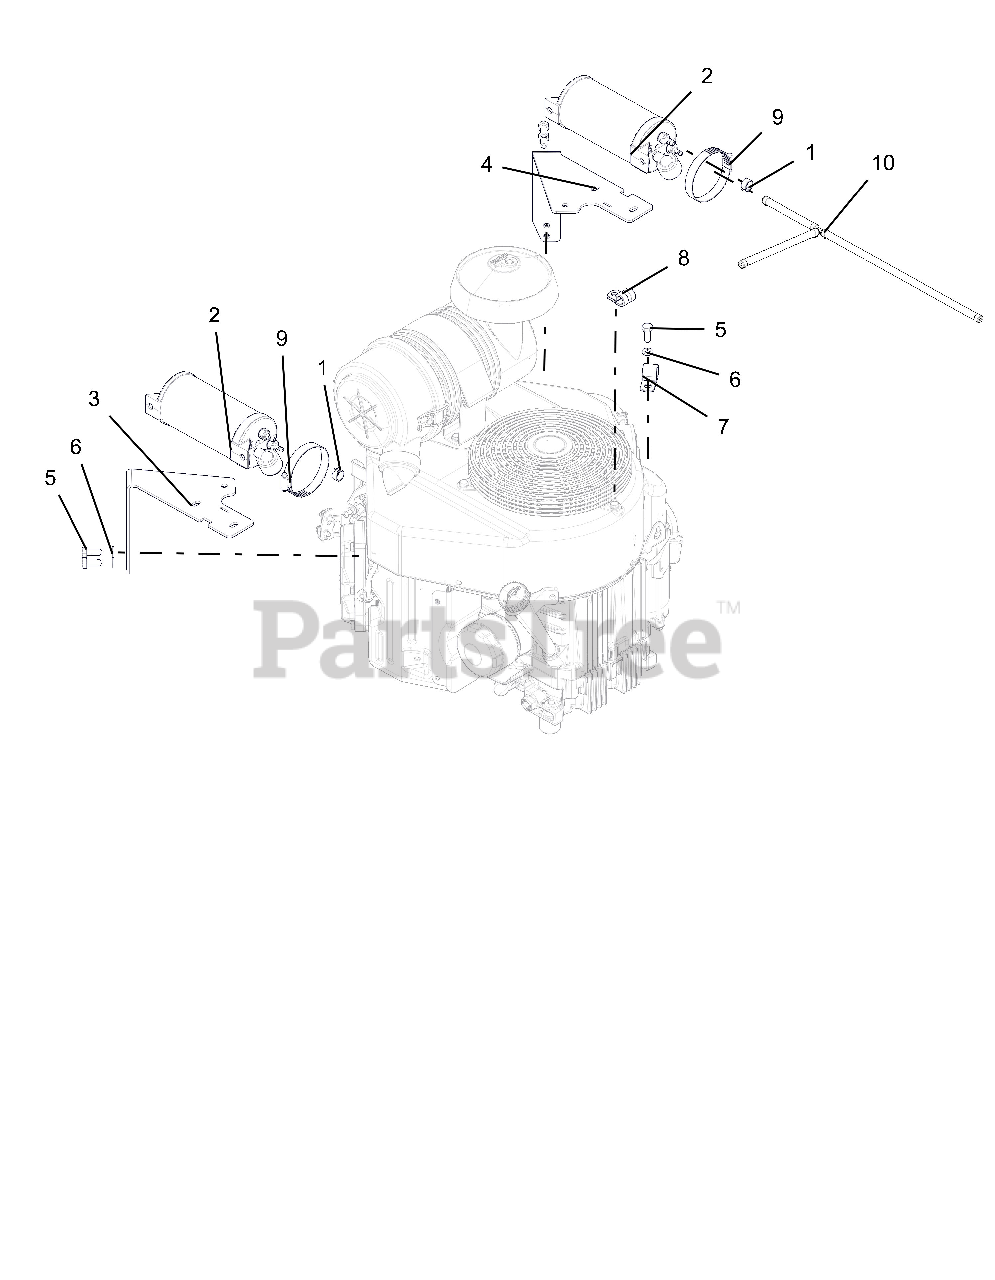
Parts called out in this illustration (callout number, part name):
1	CLAMP, FUEL LINE
2	CANISTER, CARBON 6.3 G CAP.
3	BRKT, MOUNT PT100 RH CARB CANISTER
4	BRKT, MOUNT PT100 RH CARB CANISTER
5	@BLT-HEX M8-1.25X20 YWZC
6	WSHR-LK .31X.078 REG YWZC
7	CLAMP, CUSHIONED STEEL .75
8	CLAMP, CUSHIONED STEEL
9	CLAMP, HOSE 2.3/3.2
10	ASM, FUEL LINE, PT100
